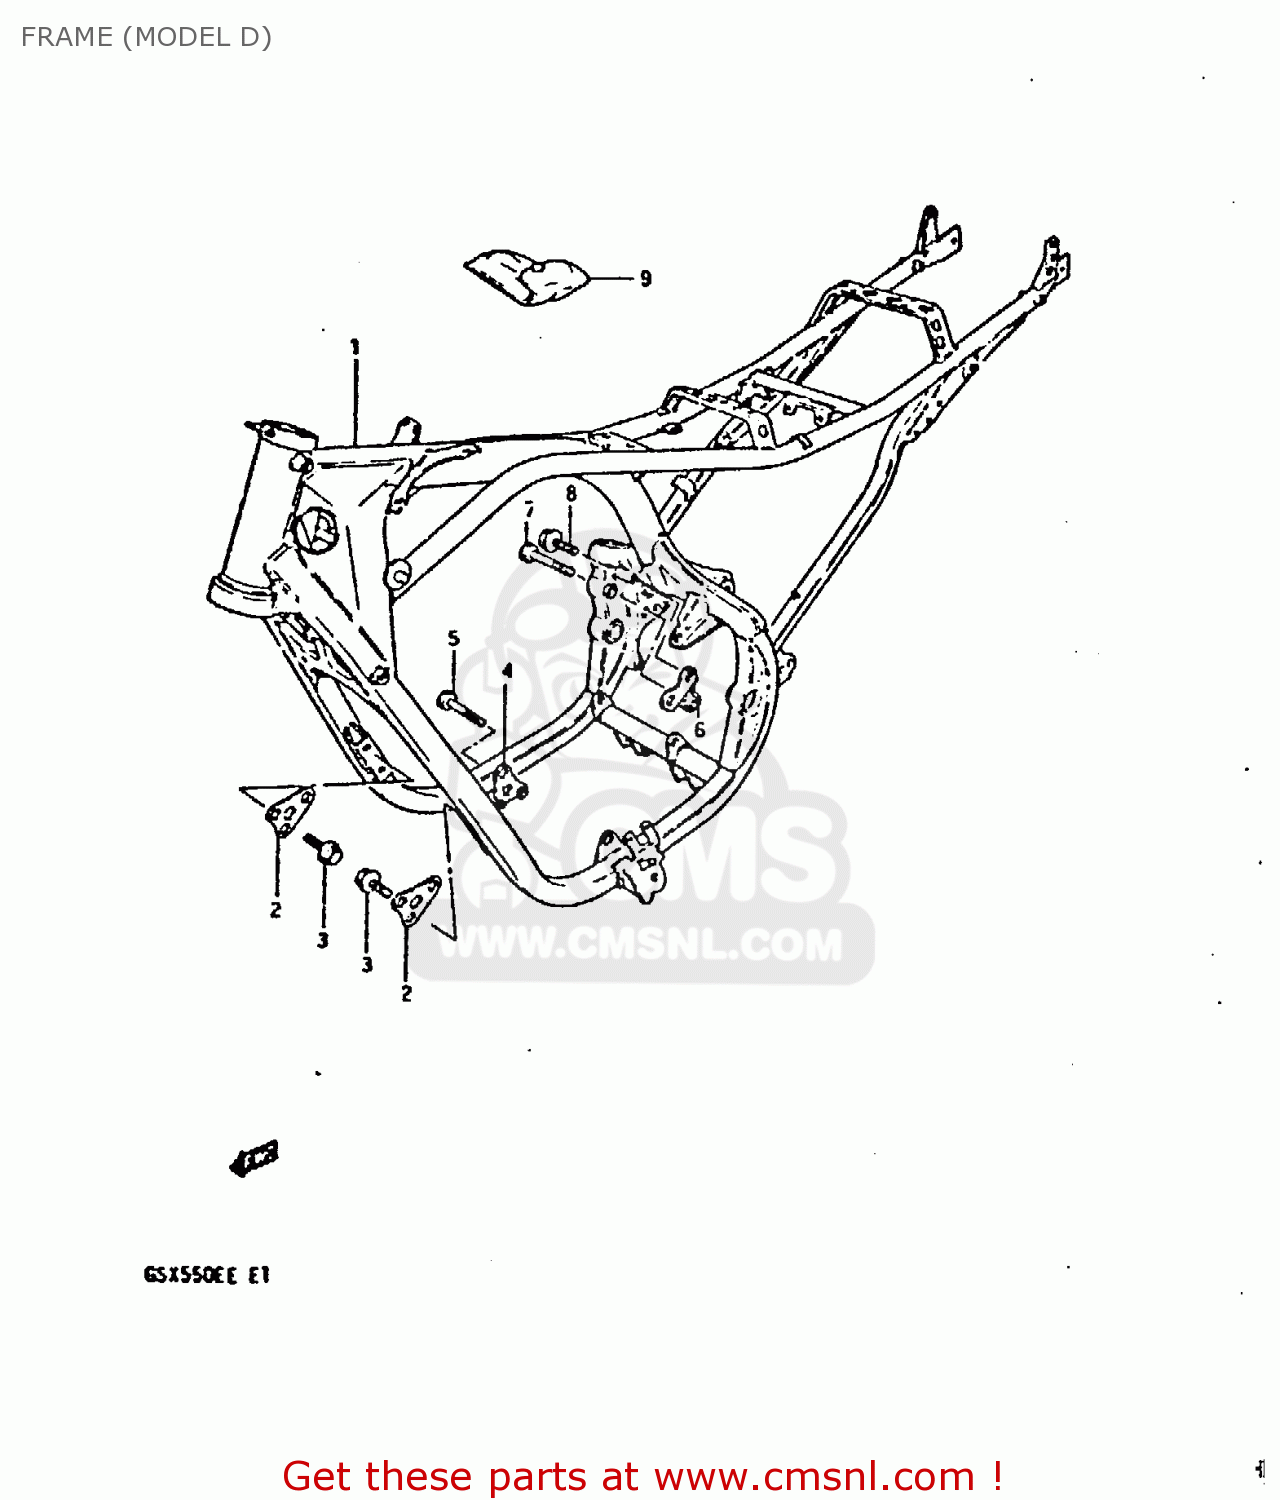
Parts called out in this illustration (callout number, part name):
1	FRAME
2	PLATE,ENGINE MOUNTING
3	BOLT
4	PLATE,ENGINE MOUNTING NO
5	BOLT
6	PLATE,ENGINE MOUNTING NO.4
7	BOLT
8	BOLT
9	TOOL ASSY
